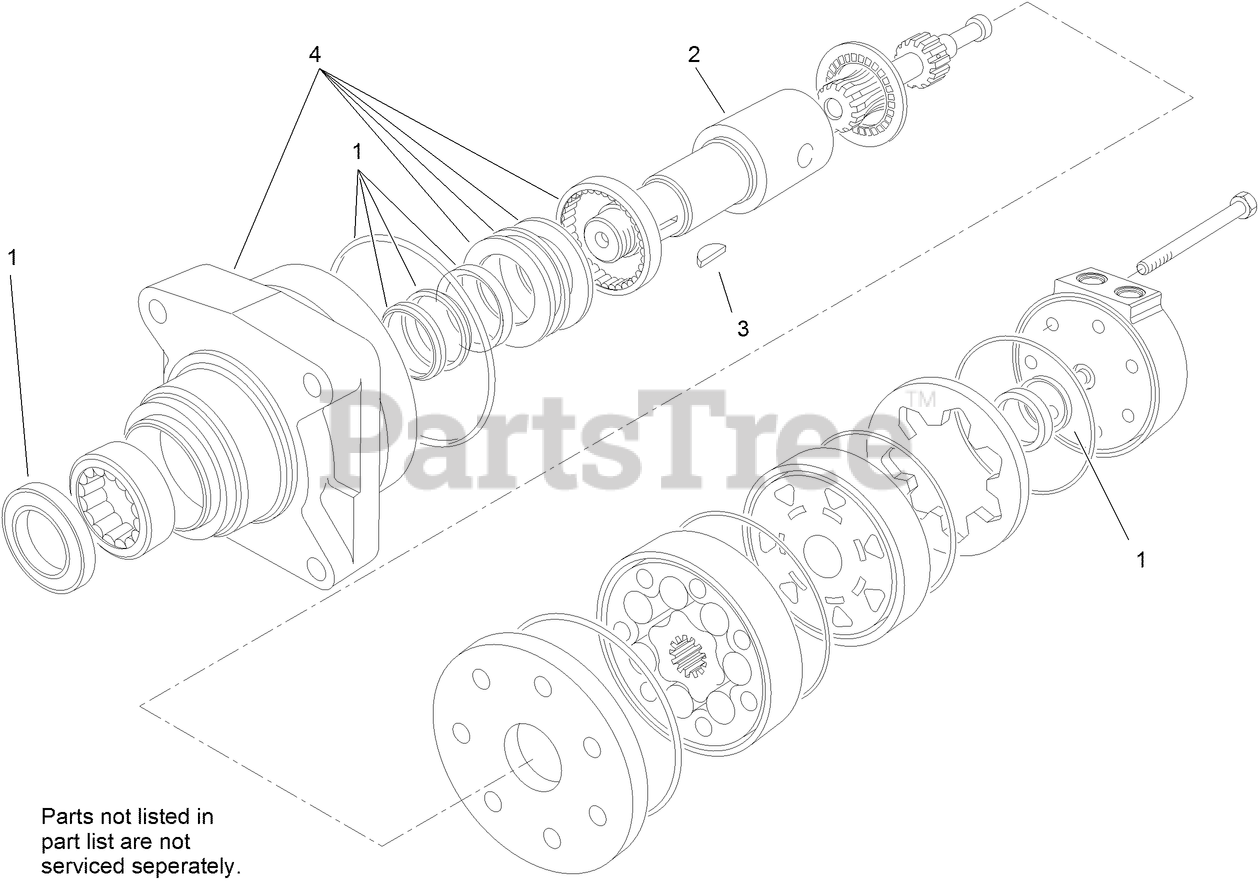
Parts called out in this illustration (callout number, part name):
1	SEAL KIT
2	COUPLING-SHAFT
3	KEY-WOODRUFF
4	MOTOR HOUSING ASM
